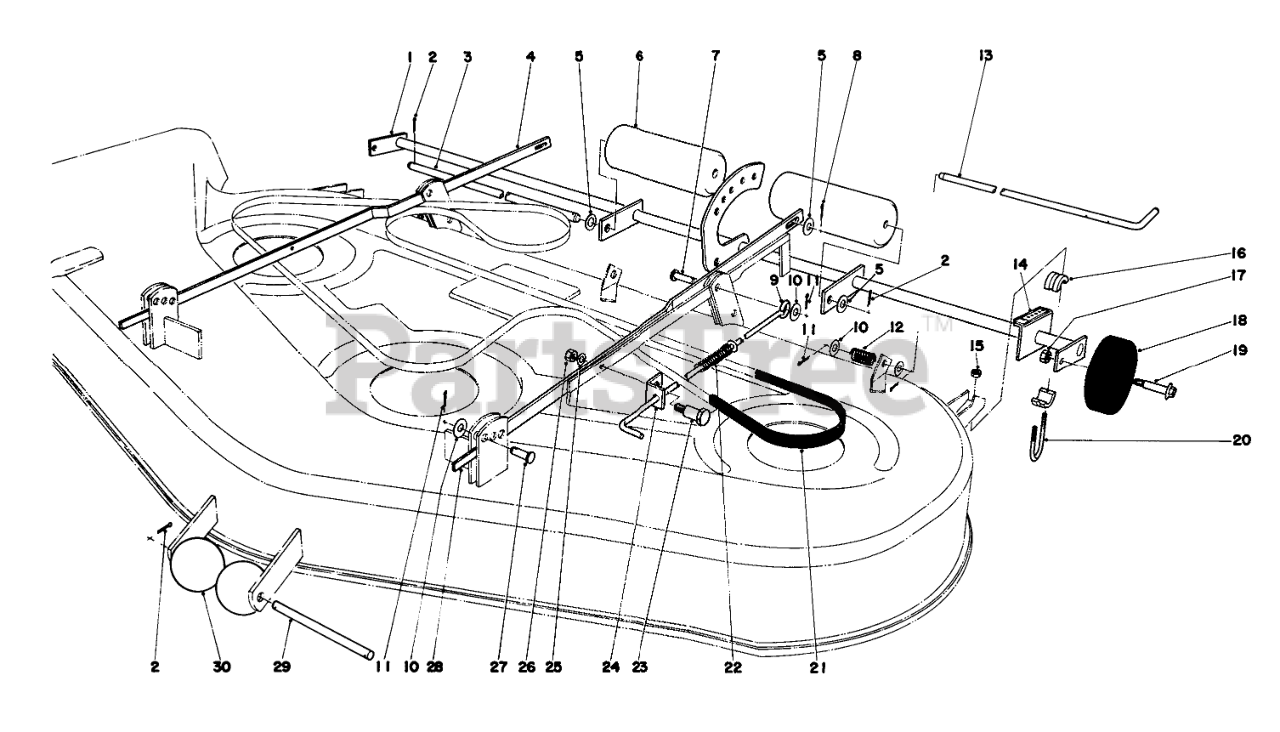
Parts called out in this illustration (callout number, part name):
1	DECK WHL SHAFT WA B
2	PIN-COTTER
3	ROLLER SHAFT B
4	RR SCISSORS LNK B
5	WASHER-FLAT
6	ROLLER-DECK
7	PIN-CLEVIS
8	PIN-COTTER
9	Pin Tension
10	WASHER-FLAT
11	PIN-COTTER
12	Spring
13	WHEEL LATCH ROD B
14	Decal-Height of Cut
15	NUT-LOCK, CONE
16	BEARING DECK SH WHEEL
17	Nut
18	DECK WHEEL
20	U-BOLT
21	V-BELT, DECK
22	COMP SPRING
23	Bolt-Shoulder
24	TENSION BELT BRKT B
25	WASHER-PLAIN
26	NUT-LOCK, CONE
27	PIN-CLEVIS
28	Scissors Link Rear L.H.
29	ROLLER SHAFT
30	Roller
